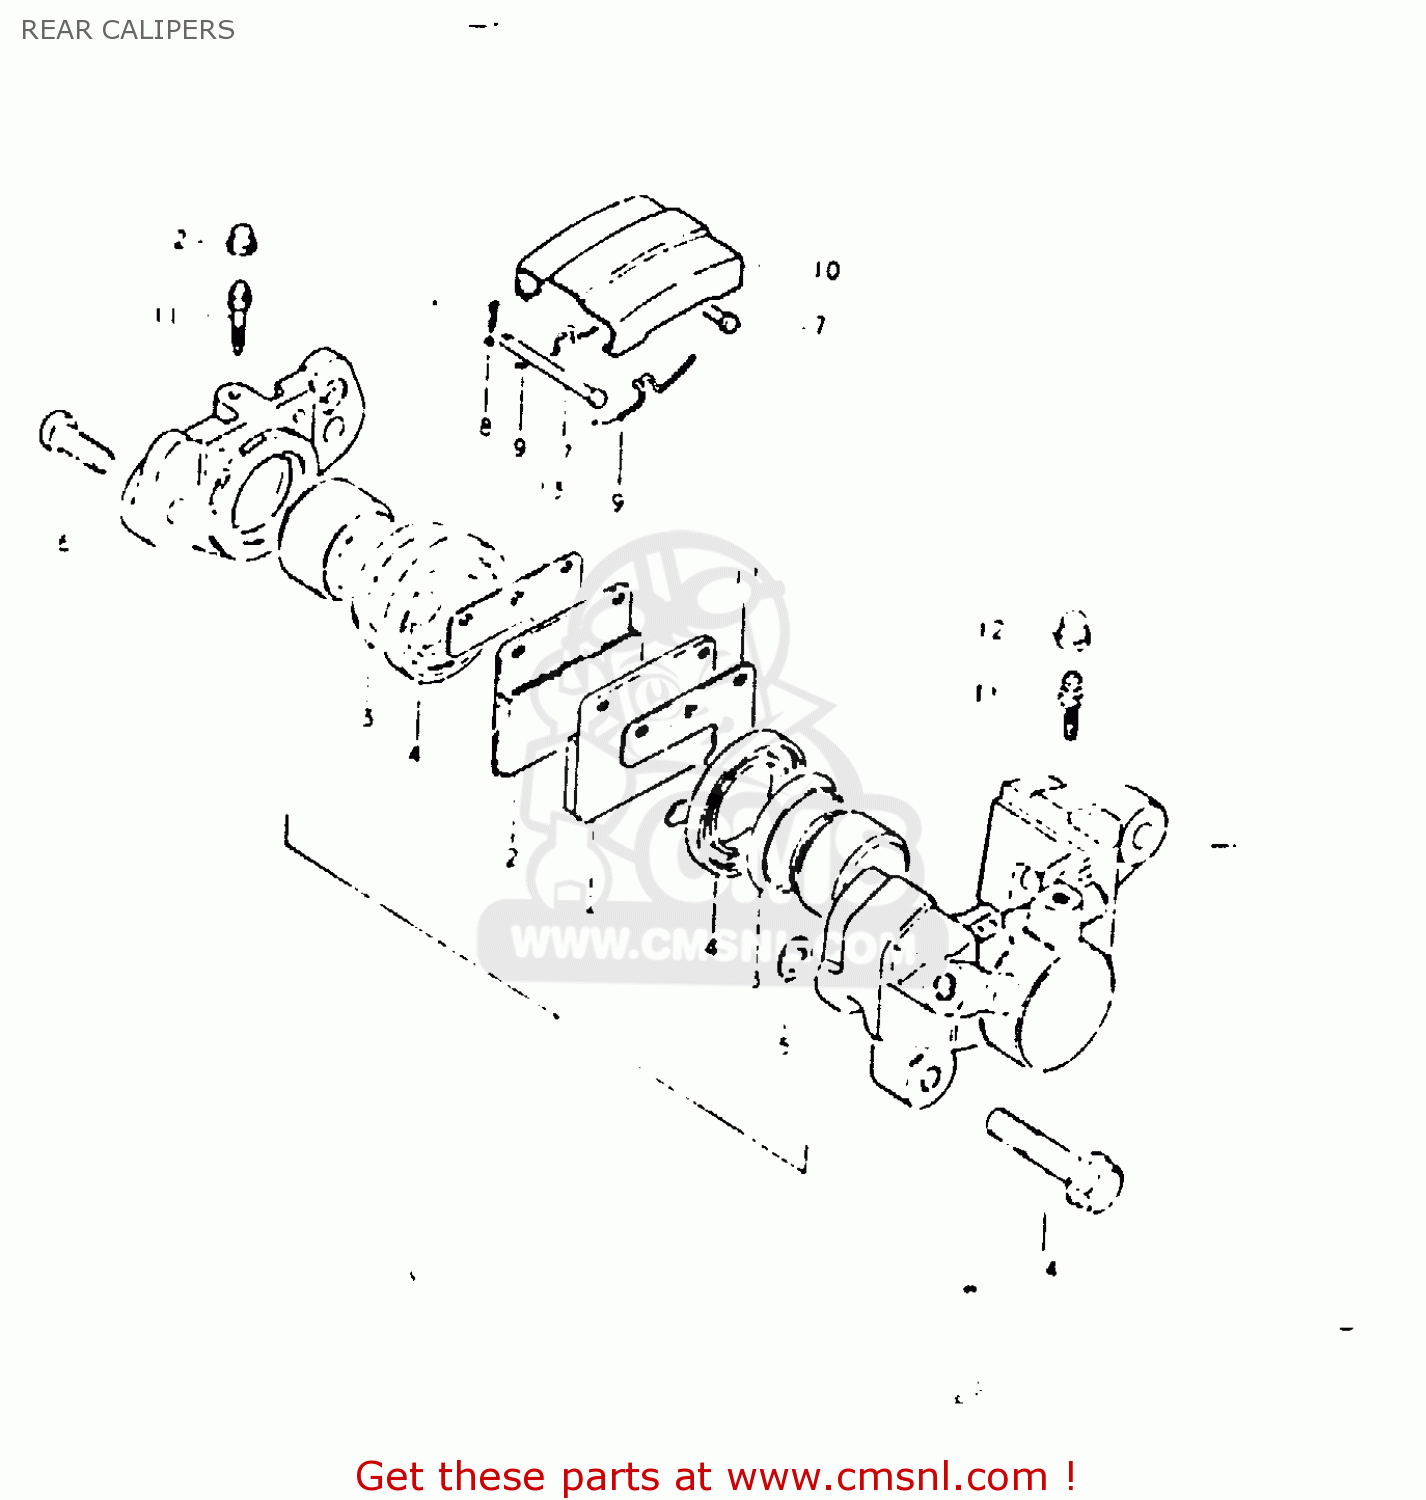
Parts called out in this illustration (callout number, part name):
1	PISTON SET
2	PAD,BRAKE
3	SEAL,PISTON
4	BOOT,PISTON
5	SEAL,PISTON
6	BOLT,HOUSING
7	PIN,PAD
8	CLIP,PAD PIN
9	SPRING
10	COVER,DUST
11	BLEEDER
12	CAP,BREATHER
13	SHIM,RR CALIPER
14	BOLT
